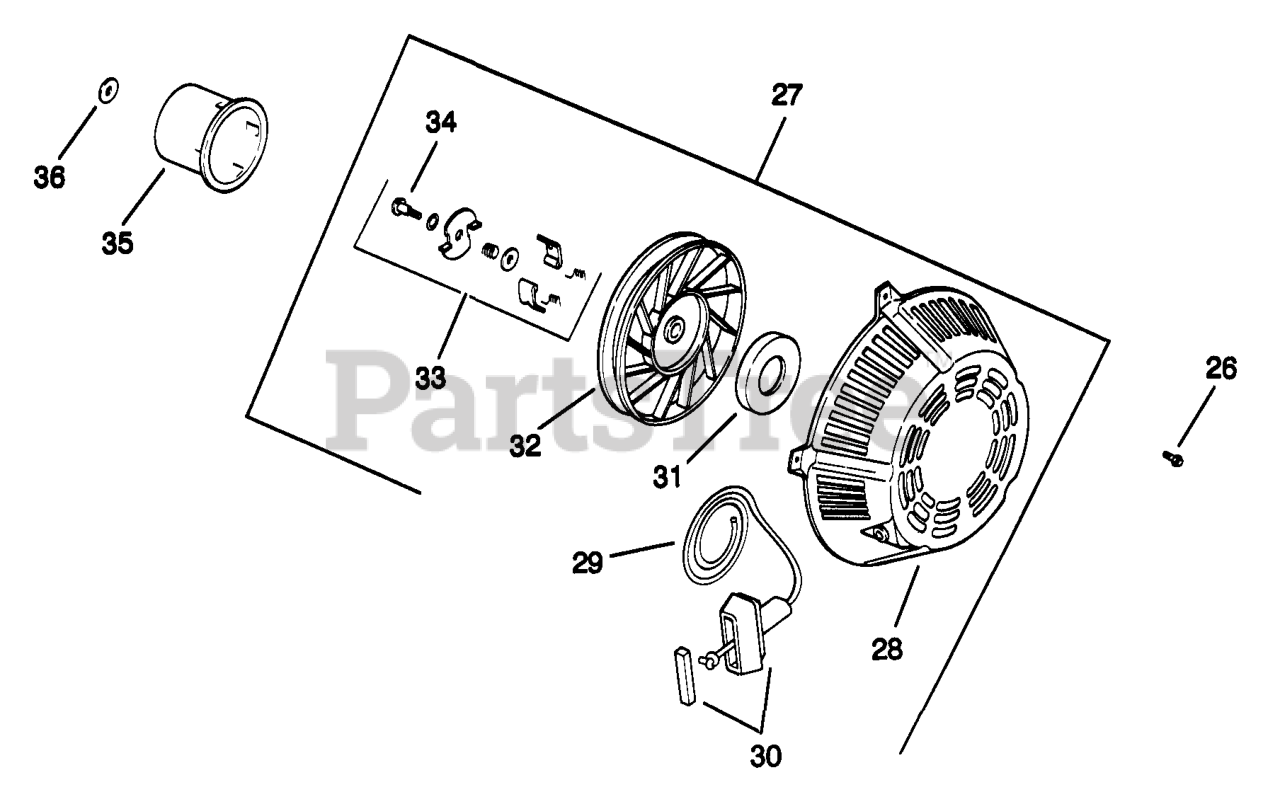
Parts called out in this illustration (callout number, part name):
26	SCREW, FLG HD 10-24X1/4"
27	STARTER ASSY,RETRACTABLE-USE 12 165 03-S
28	HOUSING - DISCONTINUED
29	ROPE - DISCONTINUED
30	HANDLE - USE 25 166 01
31	SPRING & KEEPER - (#DSC)
32	PULLEY - (#DSC)
33	KIT, DOG REPAIR - (#DSC)
34	SCREW - DISCONTINUED
36	WASHER, FLAT 13/32" - DISCONTINUED
